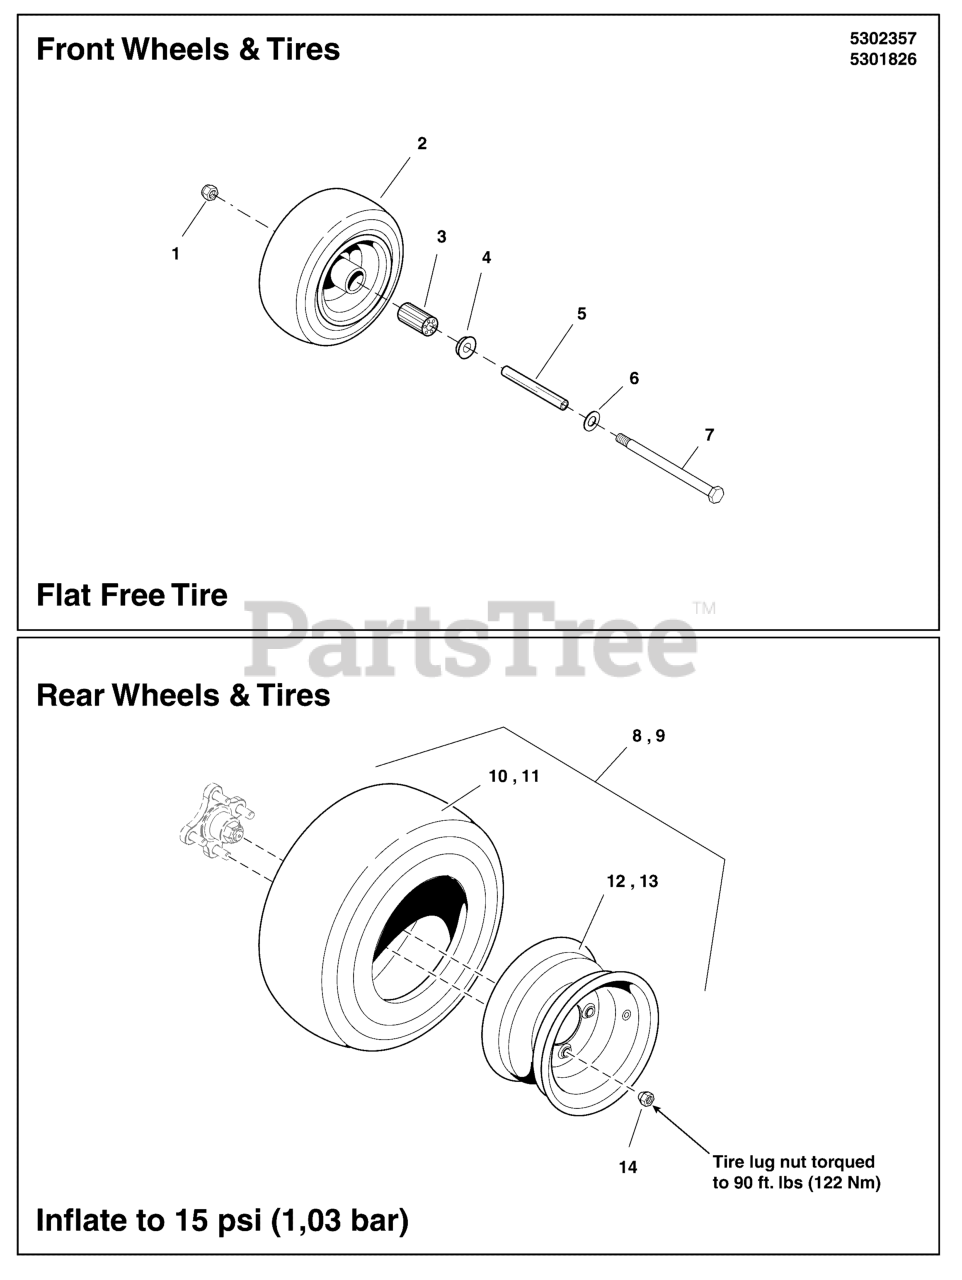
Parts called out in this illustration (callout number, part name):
1	NUT, Hex Flange, Nylock, 1/2-13
2	TIRE ASSM, 11 X 4 - 5, FF, CASTER
3	BEARING, ROLLER
4	BEARING, RETAINER
5	CASTER AXLE DDSH
6	WASHER, 1/2 SAE
7	BOLT, 1/2-13 X 7 GD5 CZ
8	TIRE ASSM, 20 X 7 - 10, TURF, 4 BOLT
9	TIRE ASSM, 20 X 8 - 10, TURF, 4 BOLT
10	TIRE, 20X7.00-10NHS, TURF MASTER
11	TIRE, REAR, 20X8X10, TURF MASTER (SV)
12	WHEEL, 10X6, 4 BOLT, NEG .700" OFFSET (SV)
13	WHEEL, 10X7.00 4/4 SOLID F237 2.625 OS
14	NUT, 1/2-20, FOR WHEEL BOLT SILVER
